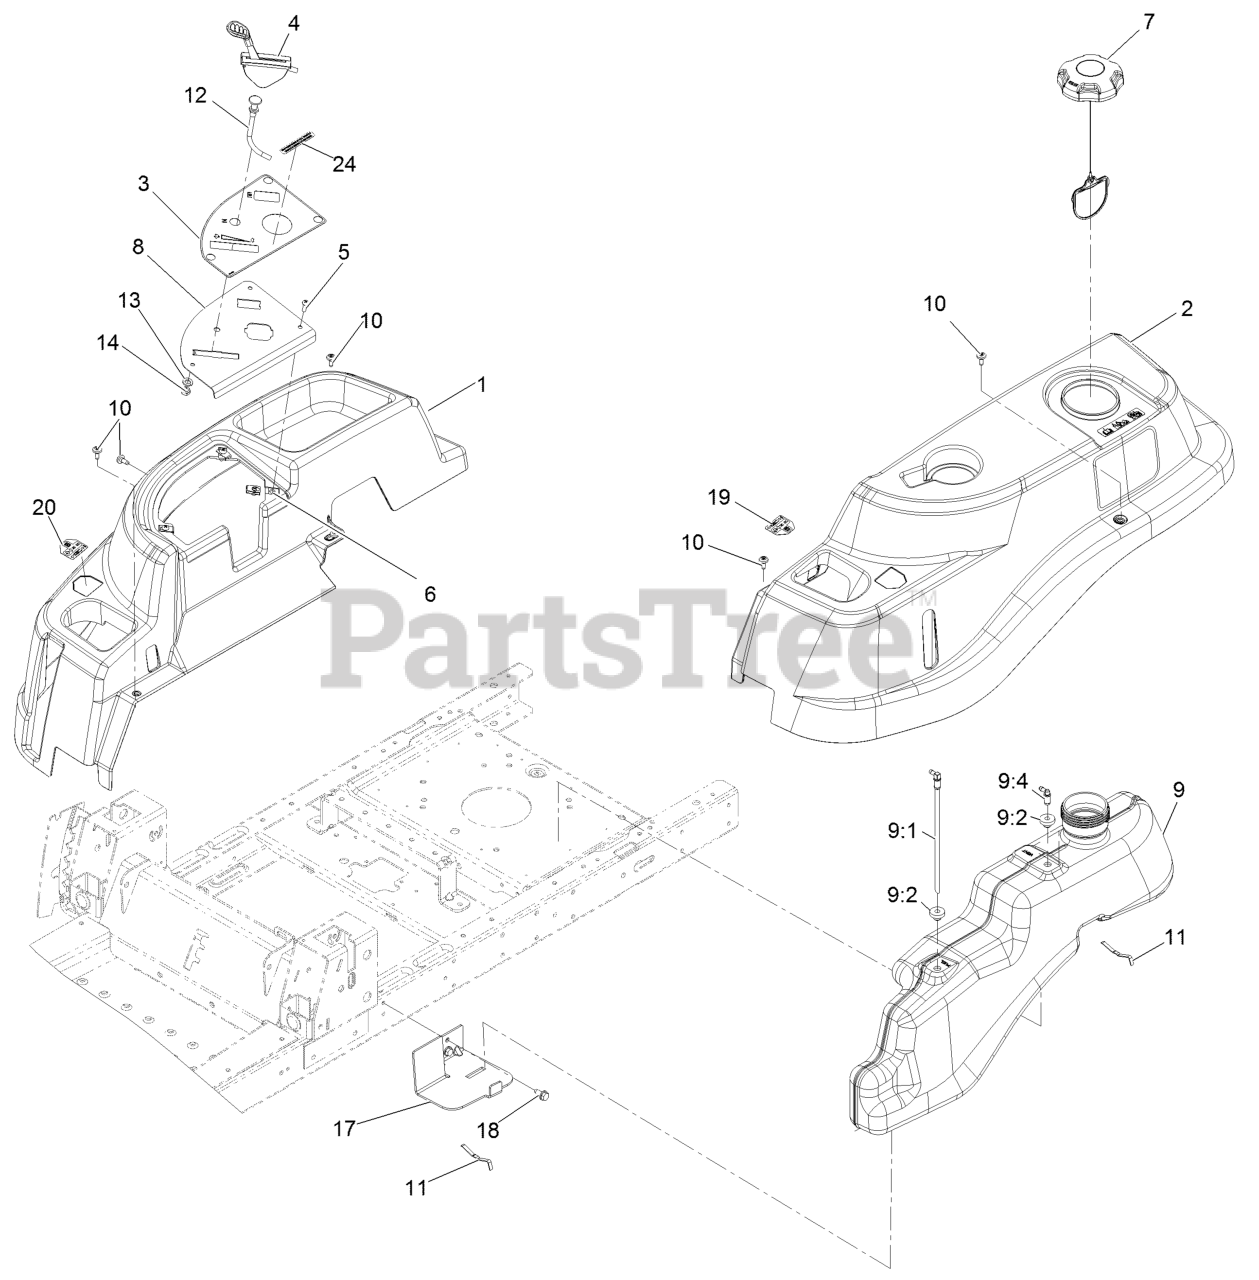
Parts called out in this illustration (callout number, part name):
3	DECAL-PANEL, CONTROL
4	CABLE-THROTTLE
5	SCREW-PRH
6	Nut-Retainer-Panel 1/4-20
8	PLATE-CONTROL
9	FUEL TANK ASM
9:1	CONNECTOR-ELBOW, 90 DEG
9:2	BUSHING
9:4	FITTING-PLASTIC
10	SCREW-SHOULDER
11	SPRING
12	CABLE-CHOKE
13	WASHER-LOCK
14	NUT-HJ
17	SUPPORT-TANK, FRONT
18	Screw-HWH 5/16-18 X 3/4 Tf
19	DECAL-LEVER, CONTROL (LH)
20	DECAL-LEVER, CONTROL (RH)
24	DECAL-SHUTDOWN
